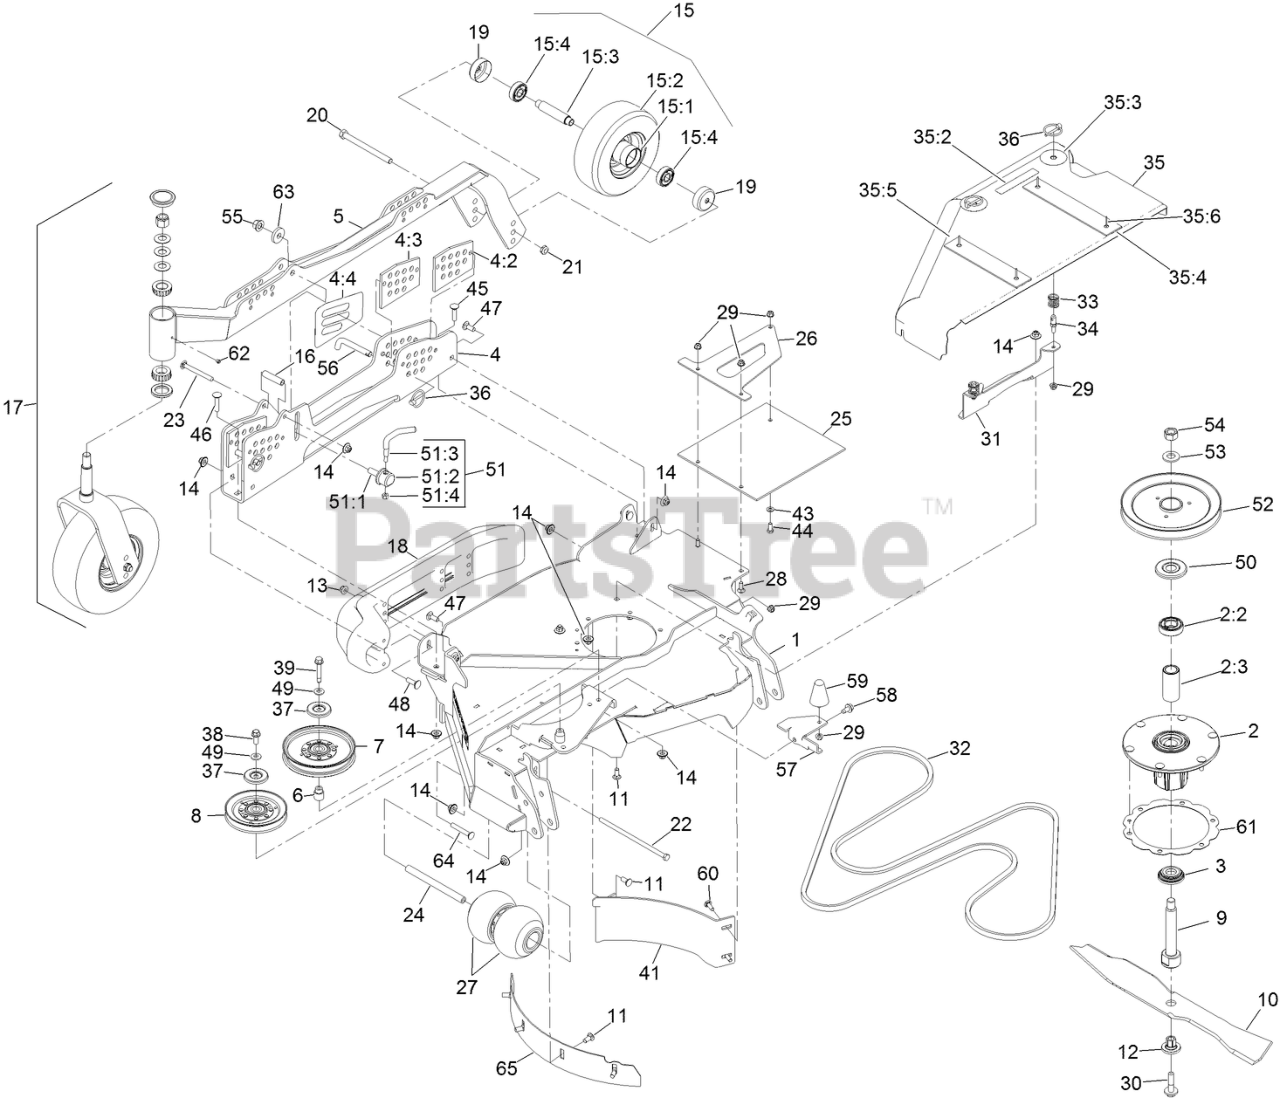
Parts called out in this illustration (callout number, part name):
1	RH WING DECK ASM
2	SPINDLE ASM
2:2	BEARING-BALL
2:3	SPACER-BEARING
3	GUARD-BOTTOM
4	RH HOC CHANNEL ASM
4:2	PLATE-GUIDE, HOC (LH)
4:3	PLATE-GUIDE, HOC (RH)
4:4	DECAL-HEIGHT OF CUT, RH
5	TUBE-HOC , RH
6	BUSHING-IDLER
7	IDLER-PULLEY
8	IDLER-V
9	SHAFT-SPINDLE
10	BLADE-24.50 MULCH
11	BOLT-CARR
12	BUSHING-HEX
13	NUT-HF, NI
14	NUT-FLANGE, NI
15	HUB and BEARING ASM
15:1	WHEEL
15:3	AXLE-CASTER
15:4	BEARING
16	SPACER
17	CASTER WHEEL ASM
18	SKID-BUMPER, DECK
19	GUARD, SEAL
20	SCREW-HH
21	NUT-HEX
22	SCREW-HH
23	SCREW-CARR
24	SPACER-WHEEL
25	GUARD-TIRE
26	SUPPORT-FLAP, RH
27	ROLLER-SCALP, ANTI
28	SCREW-CARR
29	NUT-HF, NI
30	SCREW-SEMS
31	BRACKET-SHIELD MOUNT, OUTER
32	BELT-V
33	SPRING
34	PIN, SPRING
35	RH WING SHIELD ASM
35:2	DECAL-NO STEP
35:3	DECAL-SCRATCH COVER
35:5	PLATE-FRONT
35:6	RIVET-POP
36	PIN-LYNCH
37	SHIELD-DUST
38	SCREW-HHF
39	SCREW-HHF W/ PATCH
41	BAFFLE-BLOCK, RH WING
43	WASHER-PLAIN
44	SCREW-HH
45	SCREW-CARR
46	SCREW-CARR
47	BOLT-CARR
48	BOLT-CARR
49	WASHER-BELLEVILLE
50	GUARD-BEARING, TOP
51	LEVER ASM
51:1	SCREW-LOCK
51:2	CAP-LOCK
51:4	NUT-LOCK, NI
52	SHEAVE-DRIVE, BLADE
53	WASHER
54	NUT-HEX
55	NUT-LOCK
56	PIN-HOC
57	BRACKET-COVER RETAINER
58	SCREW-HWH
59	BUMPER-RUBBER
60	SCREW-CARR
61	RING-SPACER, HOUSING
63	WASHER
64	SCREW-CARR
65	BAFFLE-DEPTH, RH
